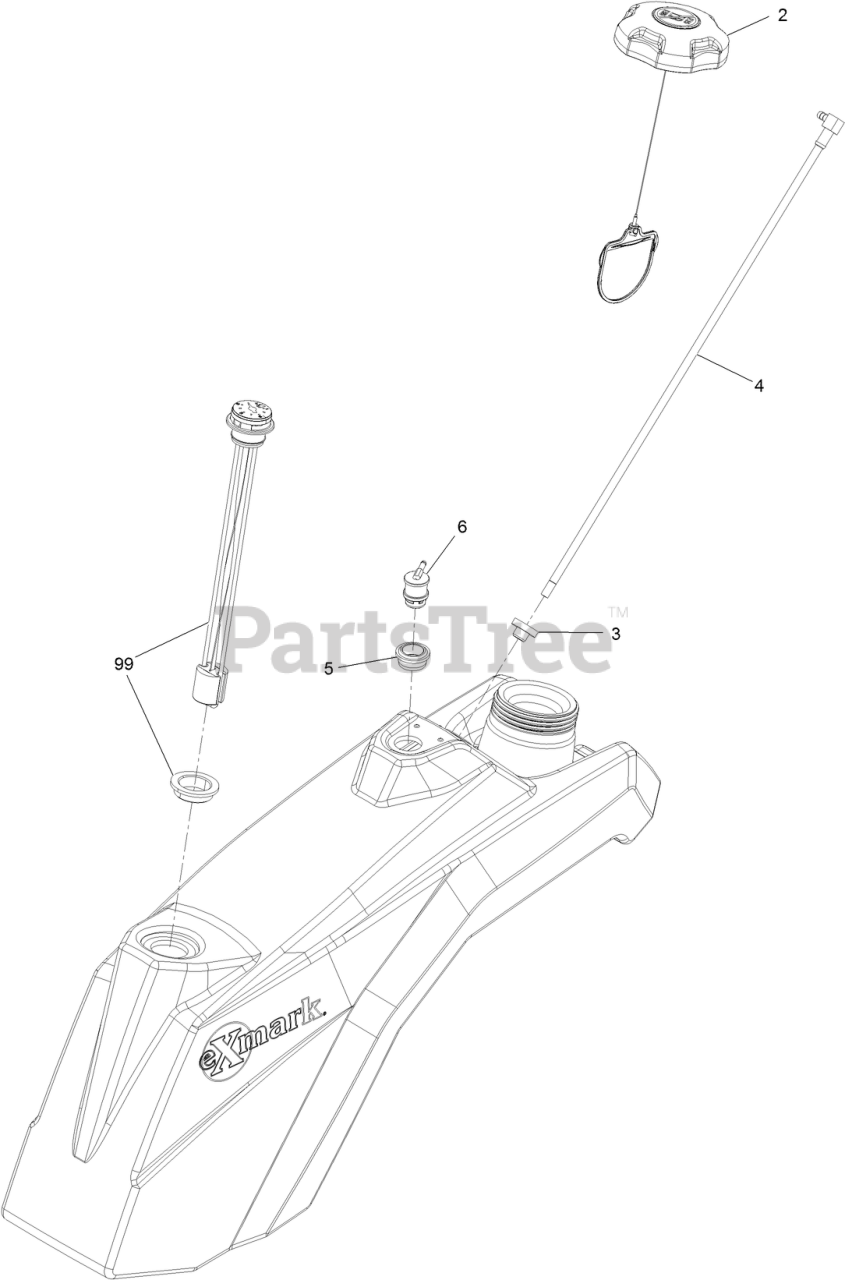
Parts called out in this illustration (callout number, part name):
2	CAP-FUEL, RATCHETING
3	BUSHING
4	STRAW, FUEL, SHORT
5	GROMMET
6	VALVE-VENT, FUEL
99	KIT, FUEL GAUGE
